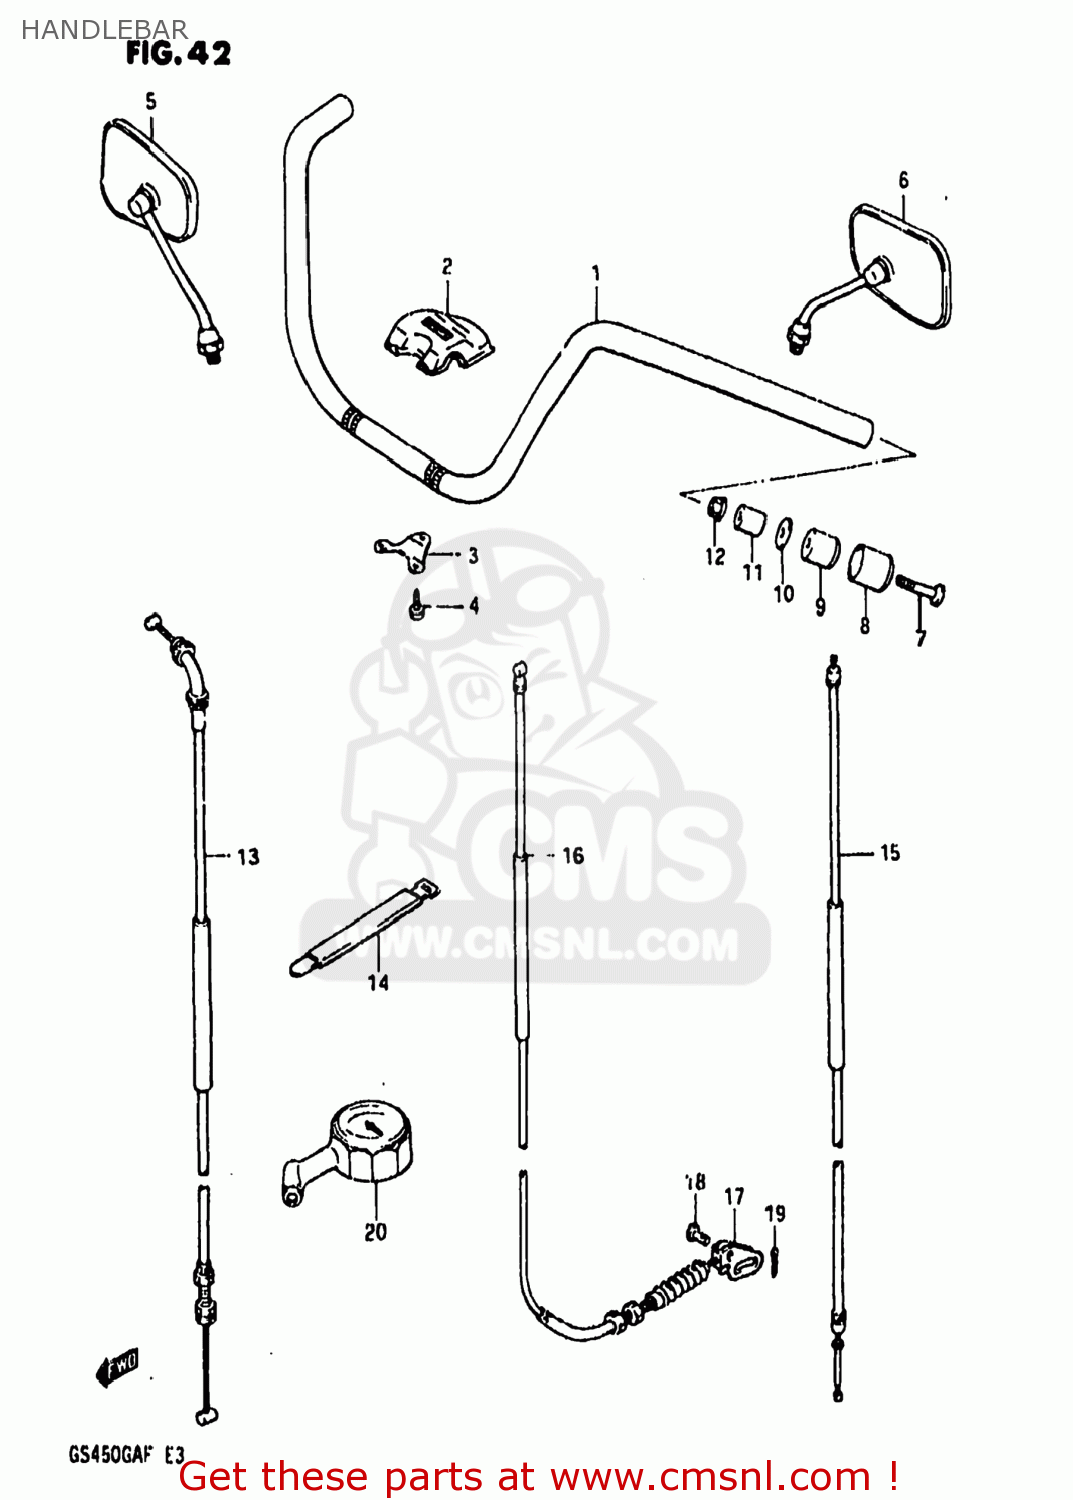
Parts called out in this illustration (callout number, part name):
1	HANDLEBAR,RIGHT
2	COVER,STEERING HEAD
3	BRACKET,HEAD COVER
4	SCREW
5	MIRROR ASSEMBLY,RIGHT
6	MIRROR ASSEMBLY,LEFT
7	SCREW
8	CAP,BALANCER
9	BALANCER,HANDLEBAR
10	SPACER,BALANCER
11	EXPANDER,HANDLE BALANCER
12	NUT
13	CABLE ASSY,THROTTLE NO.1
14	CLAMP
15	CABLE ASSEMBLY,STARTER
16	CABLE ASSEMBLY,PARKING BRAKE
18	PIN(L:13.5)
19	PIN
20	GAUGE ASSY,AIR PRESSURE
